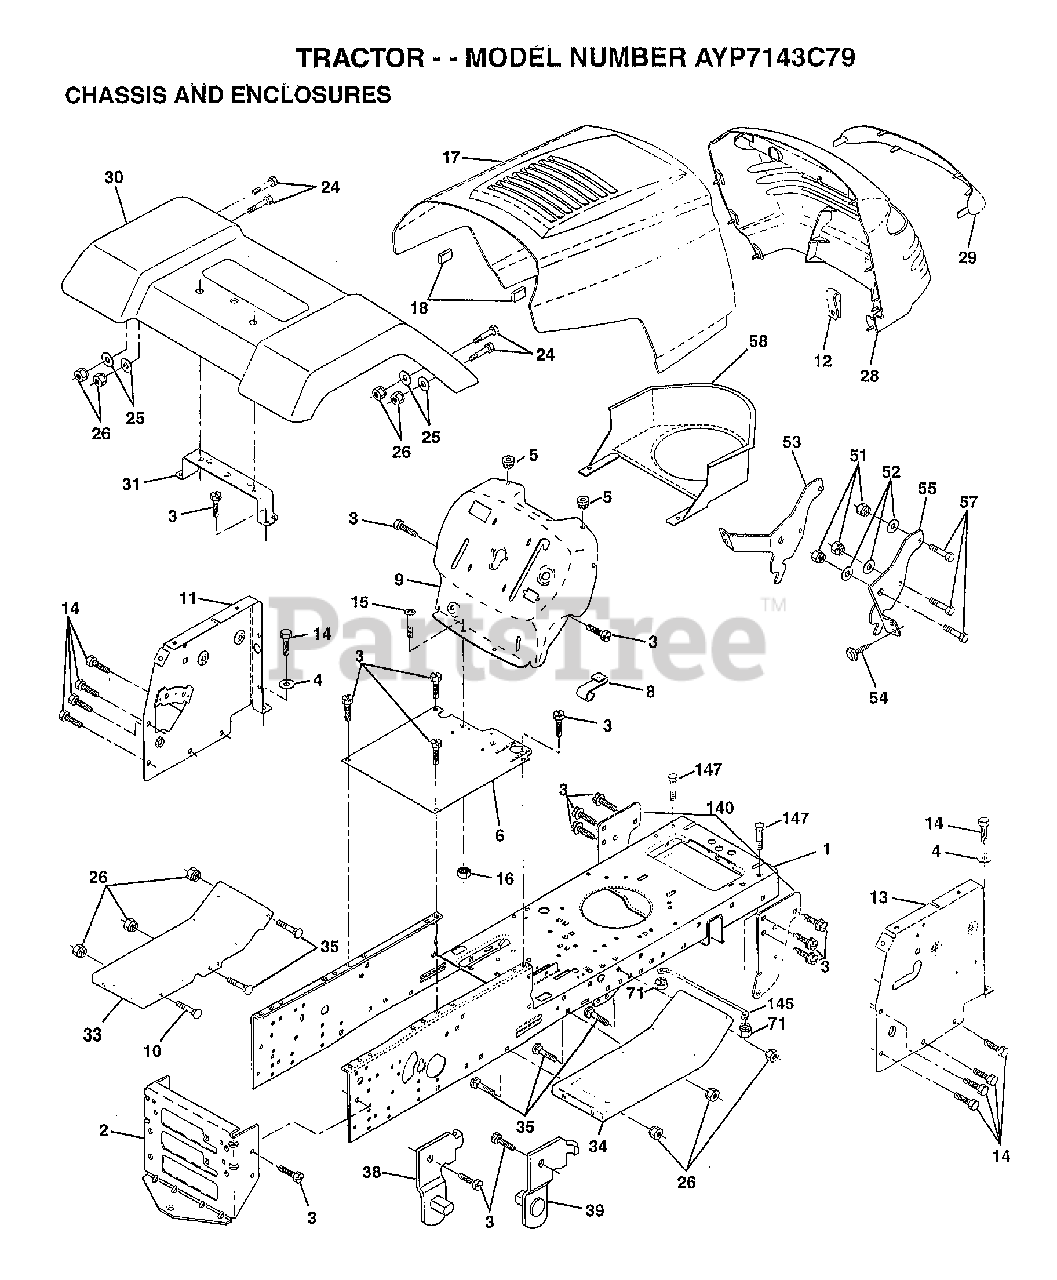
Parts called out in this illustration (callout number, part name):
1	CHASSIS ASM
3	SCREW
4	WASHER
5	BUMPER-HOOD/DASH
6	SADDLE-SILKSCREEN
8	"CLIP,INSULATOR"
9	DASH.SILKSCREENED
11	"PANEL-DASH,LH"
12	CLIP.TINNERMAN
14	SCREW LT
15	SCREW
24	BOLT
25	WASHER
26	NUT
28	GRILLE-MS428
29	LENS GRILLE
30	FENDER
31	BRKT FENDER
33	FOOTREST LH
34	FOOTREST RH
35	BOLT
38	BRACKET ASM LH
39	BRACKET ASM RH
51	NUT
52	WASHER
53	BRACKET.GRILLE.LH
55	BRACKET.GRILLE.RH
58	AIR DUCT
140	BRKT SUSPENSION
145	"ROD POVOT,CHASSIS"
147	BOLT LT
